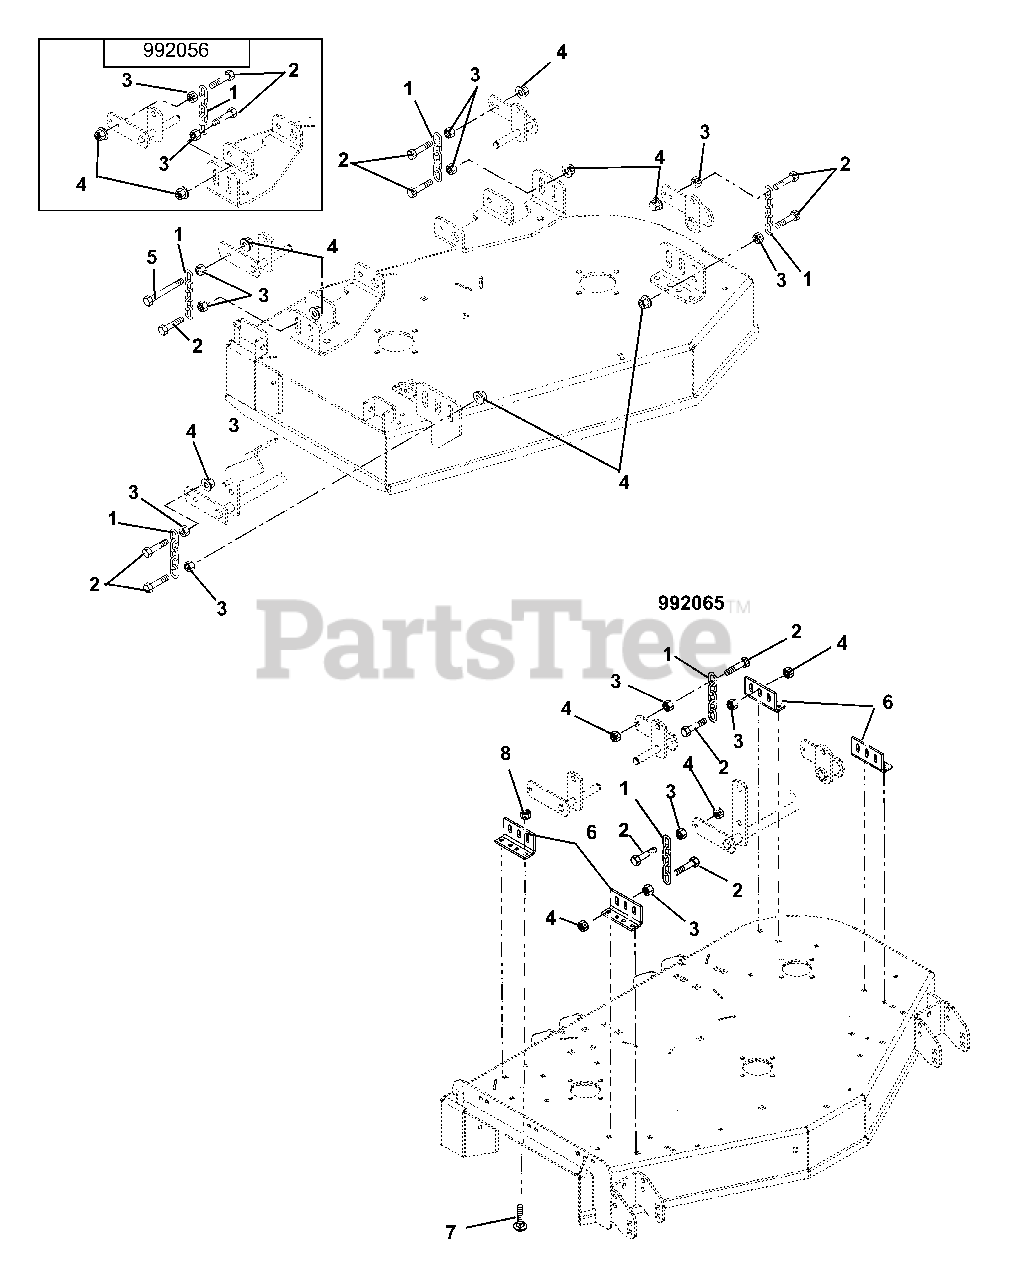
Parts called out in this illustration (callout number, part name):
1	Chain, Link
2	Bolt, Hex M12-1.75 x 55 Grade 5
3	Nut-Spin Lock-Flange M12-1.75
4	Nut-Locking-Top-Flange M12-1.75
5	Bolt-Hex .50-13 x 3.00 Grade 5
6	Bracket, Mower Mounting
7	Bolt, Round Head Square Neck .38-16 x 1.00 Grade 2
8	Nut, Locking Top Flange .38-16
